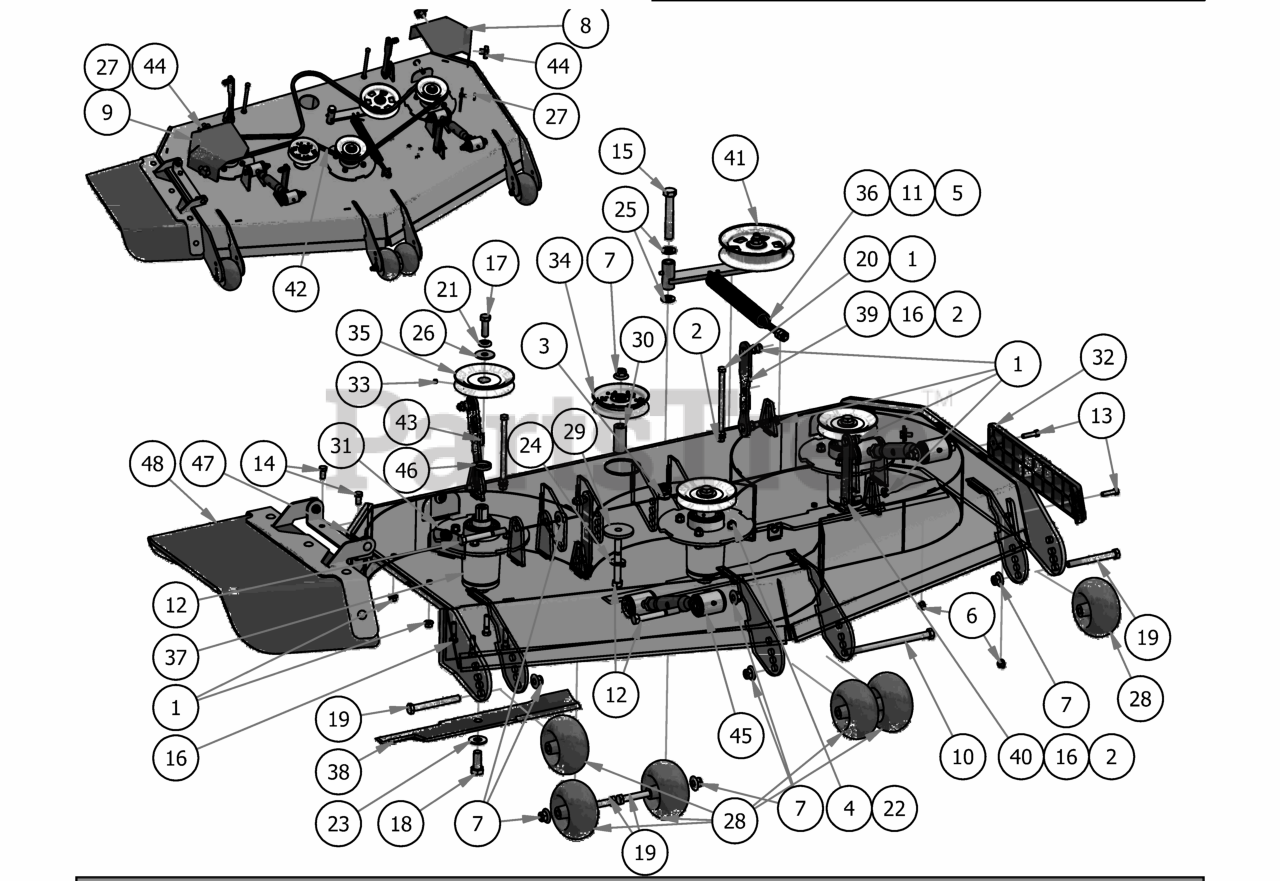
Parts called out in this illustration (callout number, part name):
1	3/8" Flange Nut
2	3/8" Nylock Flange Nut
3	5/8-11 Nylon Insert Jam Half Nut
4	3/8" Hex Nut
5	1/2" Hex Nut
6	5/16" Nylon Flange Nut
7	1/2-13 Nylon Flange Nut
8	2019 Stand On 54" Pulley Cover Trim
9	2019 Stand On 54" Pulley Cover Discharge
10	1/2-13 x 8 Hex Bolt Grade 5
11	All Thread-Pump Idler Tensioner
12	1/2" x 4" Bolt (Grade 8)
13	5/16" x 1 1/4" Hex Bolt
14	3/8" x 3/4" Hex Bolt
15	5/8" x 4" Hex Bolt
16	3/8" x 1 1/2" Hex Bolt
17	1/2"-20 x 1 1/2 - Grade 5 Fine Thread Bolt
18	5/8 x 1 1/2 Grade 8 Hex Bolt (Fine)
19	1/2" x 4 1/2" Bolt
20	3/8-16 x 5 1/2 Hex Bolt
21	1/2" Lock Washer Zinc
22	3/8" Lock Washer
23	5/8'' Flat Washer
24	1/2" Washer (Grade 8)
25	.630 ID Plastic Washer
26	1/2" Belleville Washer
27	.360 ID Plastic Washer-Black
28	2019 Deck Wheel
29	MZ Deck Idler Spacer
30	Stand On Stationary Idler Spacer
31	Deck Spindle Support Plate
32	REVISED TRIM BUMPER_20180226
33	5/16 Set Screw
34	4 3/4 Idler Pulley - ABFI-76
35	5" Spindle Deck Pulley
36	2019 Outlaw Gen2 Deck Spring
37	Spindle Assembly
38	54" Deck Fusion Blade For Outlaw
39	2019 Stand-On Rear Deck Hanger
40	2019 Stand on deck hanger_front
41	2019 Revolt Deck Idler Assembly
42	42 inch Deck Belt- B120
43	1/4" x 1" Key
44	5/16" Knob
45	Turnbuckle
46	Spacer, 1x1.375x.25
47	2019 Stand On 54" Sloped Deck Welded Assemly
48	2019 Outlaw Gen2 Chute Assembly
